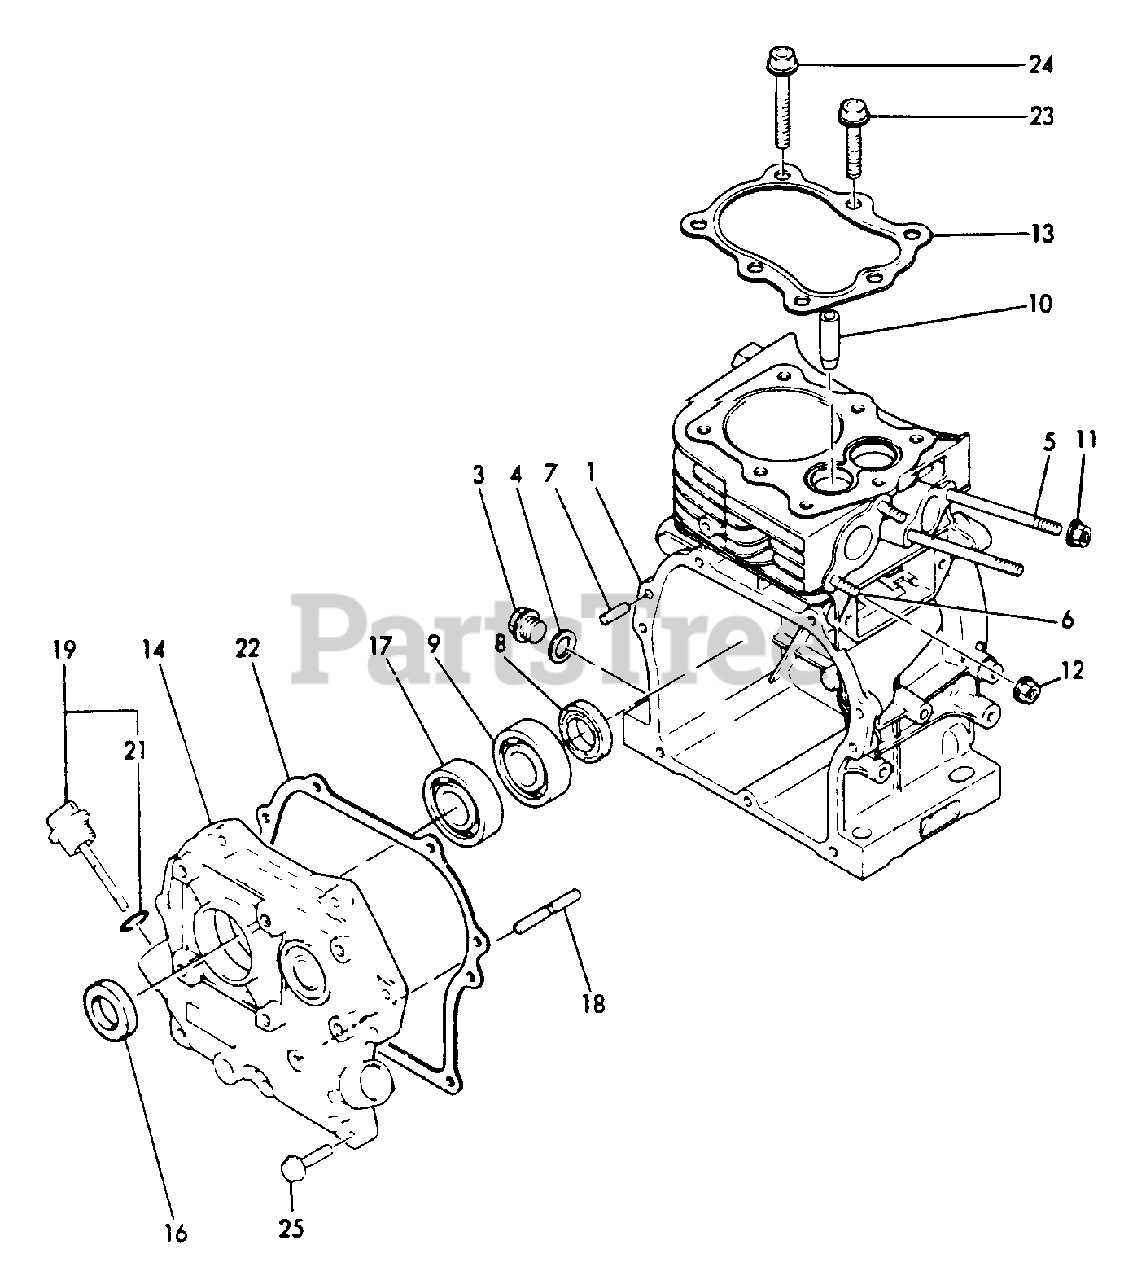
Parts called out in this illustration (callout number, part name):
1	CYLINDER BLOCK SET
3	PLUG, DRAIN
4	GASKET
5	BOLT - 6X70
6	BOLT - 6X16
7	PIN - 6X16
8	SEAL, OIL
9	BEARING, BALL - 6204C3
10	GUIDE, VALVE - EXHAUST
11	NUT - 6 -- FLANGE
12	NUT - 6 -- FLANGE
13	GASKET, CYLINDER
14	SIDE COVER ASSY
16	SEAL, OIL
17	BEARING, BALL - 6204C3
18	SHAFT, GOVERNOR
19	CAP ASSY
21	O-RING - 18
22	GASKET
23	BOLT - 8X39
24	BOLT - 8X60
25	BOLT - 6X25
